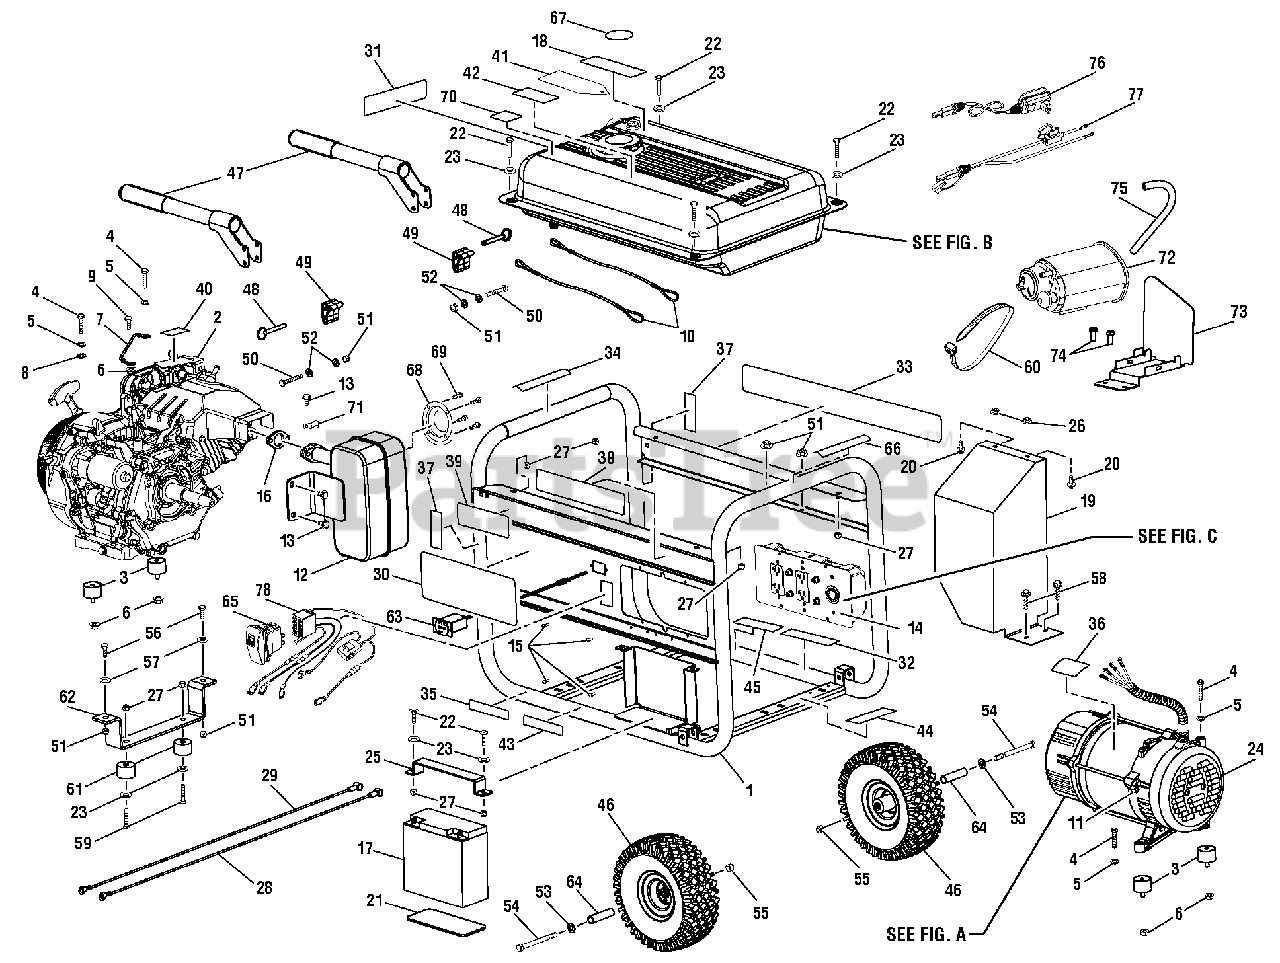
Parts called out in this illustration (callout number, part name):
1	Carrier Assembly
4	Bolt (5/16-18 x 1-1/2 in., Hex Hd.)
5	Lock Washer (5/16 in.)
6	Flange Nut (5/16-18, Hex Hd.)
7	Ground Wire Assembly
8	Star Washer (5/16 in.)
9	Bolt (5/16-18 x 3/4 in., Hex Hd.)
10	Lanyard (3/16 in.)
11	Ground Lug
13	Bolt (5/16-24 x 5/8 in.)
14	Control Panel Assembly
15	Screw (6-20 x 3/8 in.)
16	Muffler Gasket (supplied by Honda)
17	Battery
18	Minimum Fuel Octane Label
19	Heat Shield
20	Bolt (M6 x 12 mm)
21	Battery Box Gasket
22	Bolt (1/4-20 x 1 in., Hex Hd.)
23	Washer (1/4 in.)
24	Generator Head w/AVR
25	Battery Hold Down Bracket Assembly
26	Flange Nut (M6)
27	Lock Nut (1/4-20)
28	Battery Cable (Red)
29	Battery Cable (Black)
30	Logo Label
31	Starting Instructions Label
32	Hot Surface Label
33	Danger Label
34	Fire Danger Label
35	Engine Lubricant Label
36	Data Plate Label
37	Locking Pin Label
38	Honda Label
39	Electric Start Label
40	Choke Label
41	Oil Hangtag
42	CPSC Label
43	Inquiries Label
44	Ground Warning Label
45	Combustion Warning Label
46	Wheel Assembly
47	Handle Assembly
48	Release Pin (5/16 x 2 in.)
49	Handle Bracket Spacer
50	Bolt (5/16-18 x 2-1/4 in., Hex Hd.)
51	Lock Nut (5/16 in.)
52	Washer (5/16 in.)
53	Washer (3/16 in.)
54	Bolt (3/8-16 x 4-1/4 in., Hex Hd.)
55	Nut (3/8-16)
56	Bolt (5/16-18 x 1 in., Hex Hd.)
57	Flat Washer (5/16 in.)
58	Screw (#8 x 3/4 in.)
59	Bolt (1/4-20 x 1-1/2 in., Hex Hd.)
60	Cable Tie
61	Rubber Foot
62	Front Foot
63	Hour Meter (120 Volt)
64	Wheel Spacer
65	Engine Switch
66	Fire Distance Label
67	Fuel Stabilizer Label
68	Spark Arrestor
69	Screw (M5 x 19 mm, Pan Hd.)
70	E85 Label
74	Bolt (#10 x 1 in.)
75	Purge Hose
76	Battery Charger
77	Wiring Harness (DC Charger)
78	Wiring Harness (Switch)
